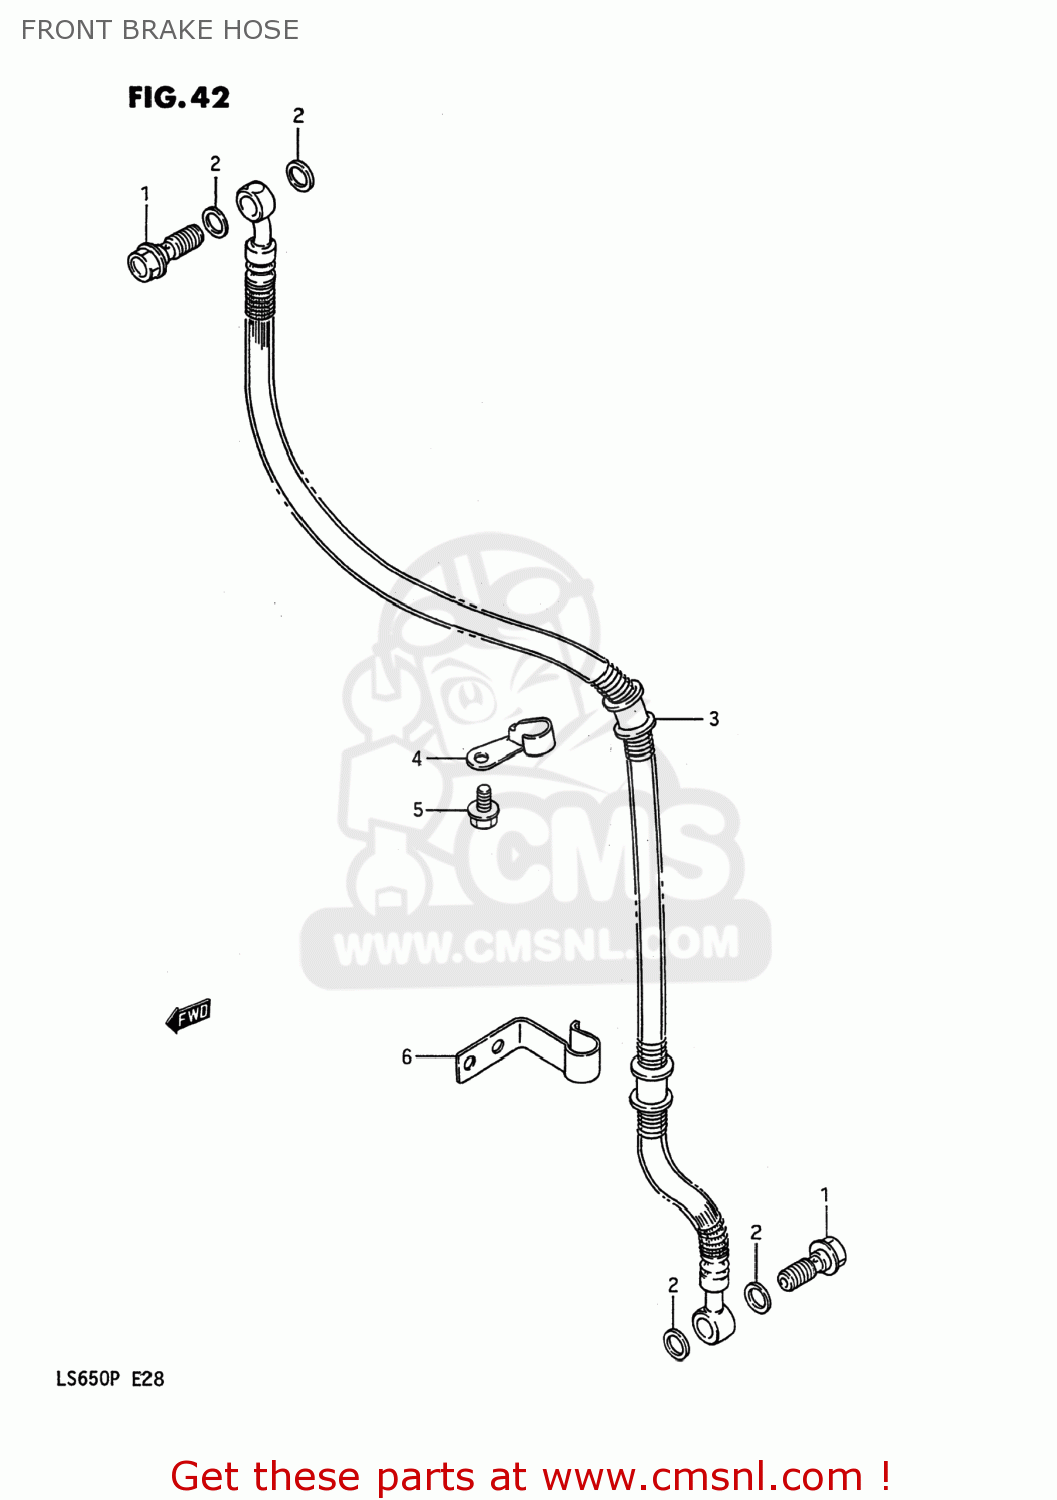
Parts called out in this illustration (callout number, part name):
1	BOLT UNION
2	WASHER(10X15X1.5)
3	HOSE,FR BRAKE
4	GUIDE,BRAKE HOSE NO.1
5	BOLT
6	GUIDE,BRAKE HOSE NO.2
